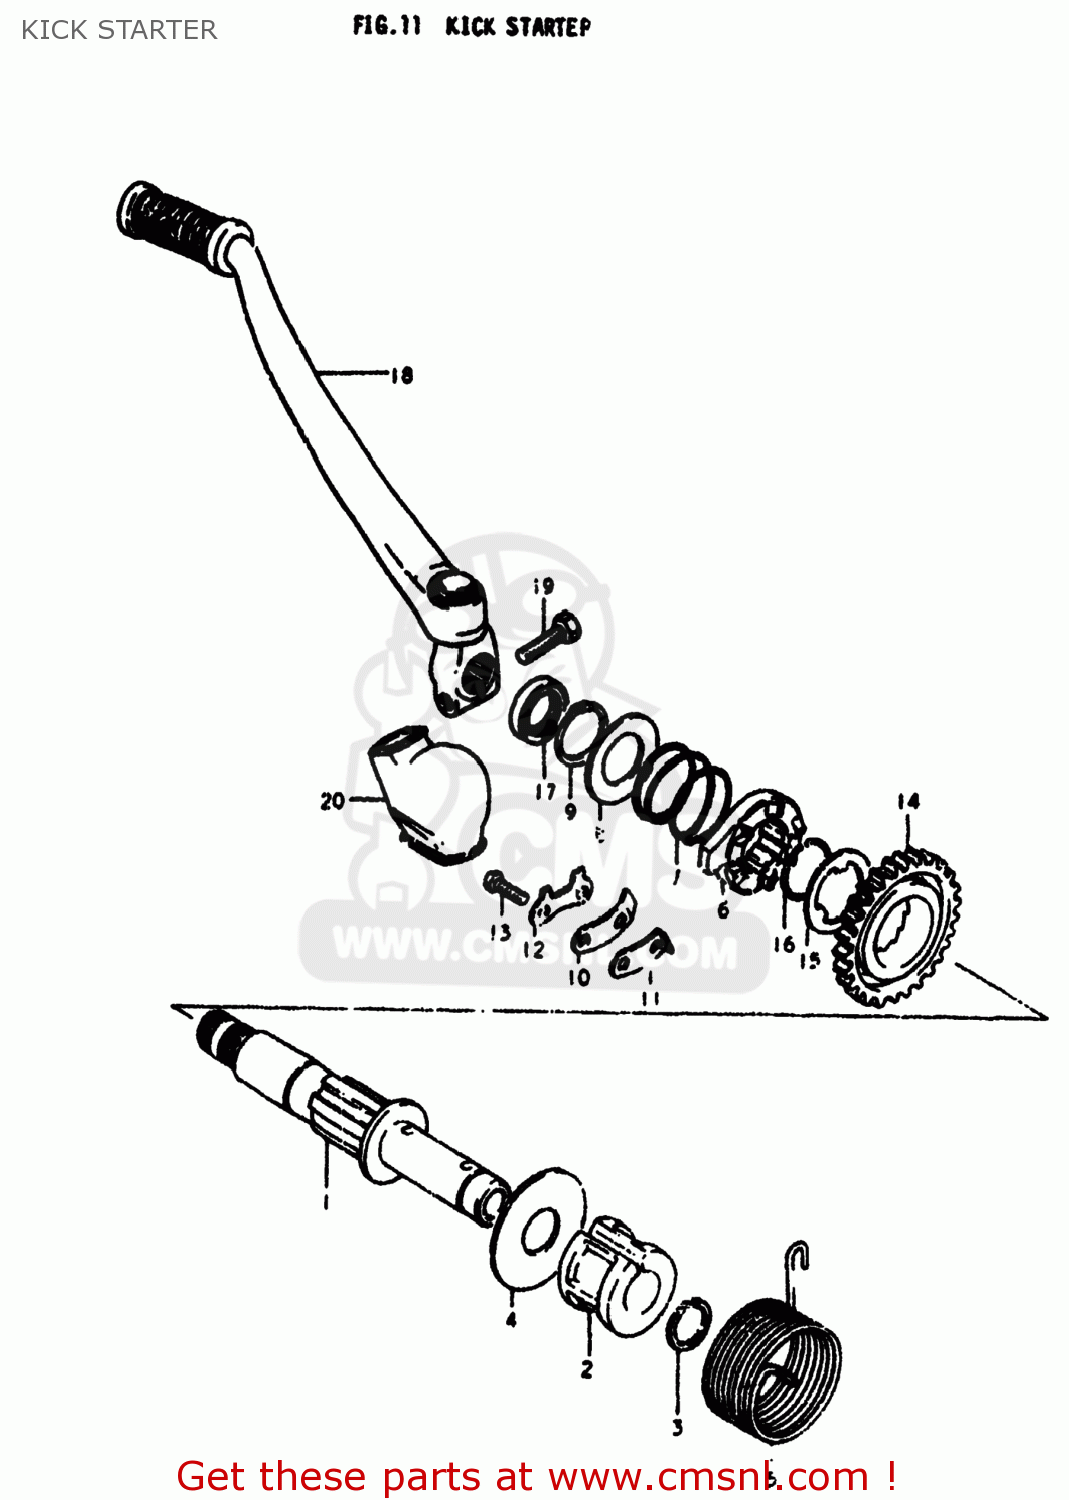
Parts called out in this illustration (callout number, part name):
1	SHAFT,KICK STARTER
2	GUIDE,KICK SHAFT SPRING
3	CIRCLIP
4	WASHER
5	SPRING
6	STARTER,KICK
7	SPRING
8	WASHER
9	CIRCLIP
10	GUIDE,KICK STARTER
11	STOPPER,KICK STARTER
12	WASHER
13	BOLT, UPPER
14	GEAR,KICK STARTER DRIVE
15	WASHER,LOCK
16	RING,SNAP
17	SEAL,OIL(20X27X5)
18	LEVER ASSEMBLY,KICK STARTER
19	BOLT(8X25)
20	COVER,KICK LEVER JOINT
